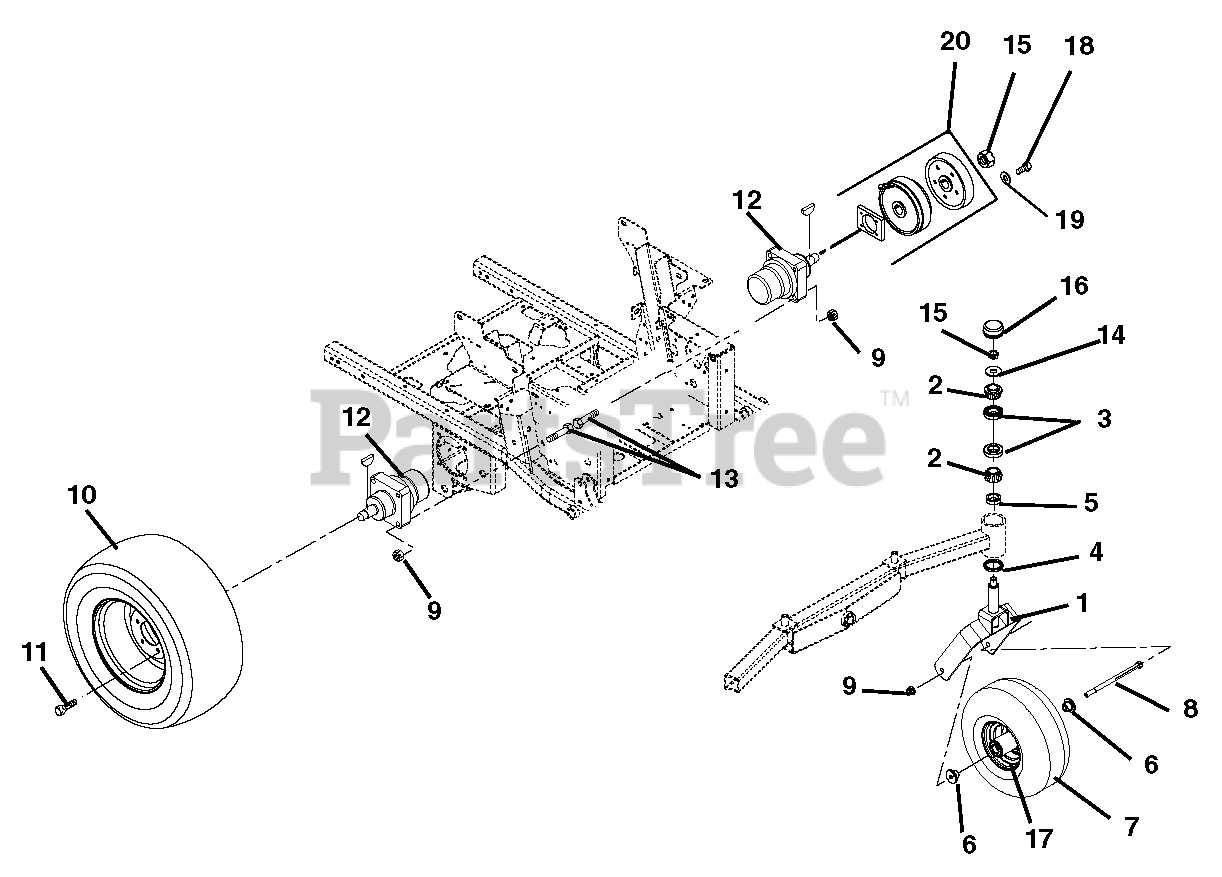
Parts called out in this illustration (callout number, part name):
1	Fork, Front
2	Bearing, Cone
3	Bearing, Cup 1.98 x .420
4	Bearing Seal 1.5 x 2 x .18
5	Spacer, PM, 1.03 I.D. x 1.5 O.D. x .375
6	Spacer, Wheel
7	Wheel/Tire Assembly
8	Bolt, Hex .50-13 x 9.00 Grade 5
9	Nut, Locking Top Flange .50-13
10	Tire/Wheel Assembly, 24 x 11.50-12
11	Bolt, Lug .50-20 x 1.38
12	Wheel Motor, Parker
13	Bolt, Wheel Motor .50-13 x 2.75
14	Washer, Flat Steel, .812 x 2.00 x .148
15	Nut, Locking-Jam-Patch 1.00-20
16	Cap, Dust
17	Bearing, 25mm I.D. x 52mm OD x 15mm
18	Bolt, Hex .31-18 x 1.5 Grade 5
19	Washer, Lock .31 x .078
20	Kit, Parking Brake Service
21	Key, Woodruff .31 x 1.00
22	Kit, Parker TF Motors Seal
